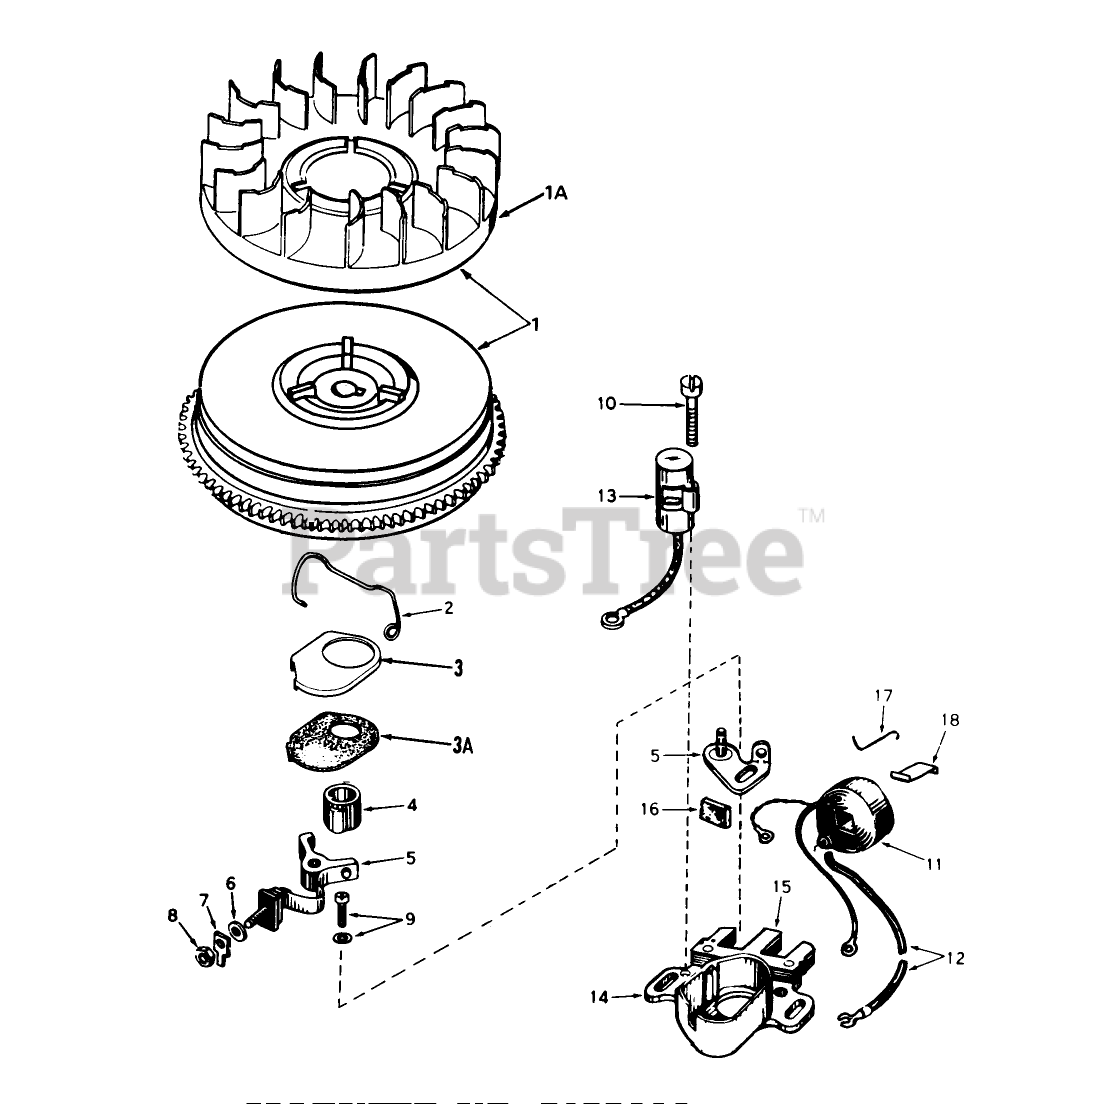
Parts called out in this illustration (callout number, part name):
1	Flywheel (Incl. Nos. 1A, 3 3A)
2	Spring Breaker Box
3	Cover-Dust
3A	Gasket, Dust Cover
4	Cam-Breaker
5	Breaker Assy.
6	Washer
7	Terminal, Ground
8	DECAL
9	Breaker Screw
10	Condenser Screw
11	Coil Assy. (Incl. No. 12)
12	Wire, Lead
13	Condenser
14	Core Plate
15	Stator Assy. (Incl. Ref. #2 thru 11, 13, 14, 16, 17 19)
16	Felt,Cam Wiper
17	Clip, Coil
18	Spring Coil Wedge
